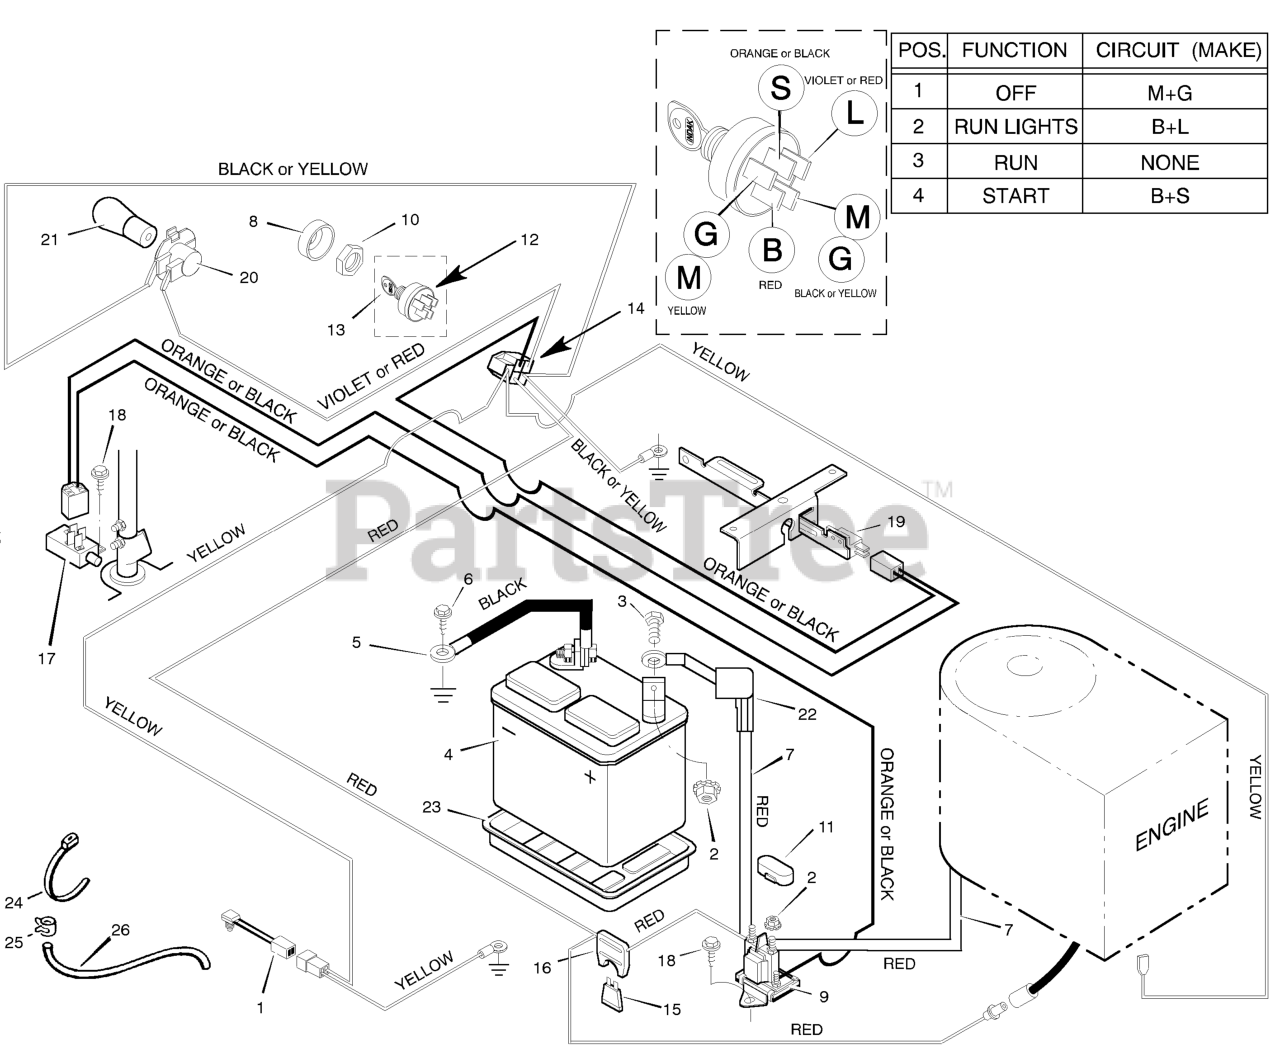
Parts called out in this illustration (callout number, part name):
1	Switch, Seat Sensor
2	Locknut
4	Battery
5	Cable, Battery Ground
7	Cable, Red Battery
8	Cap, Ignition
9	Solenoid
10	Nut, Hex
11	Cover, Solenoid
12	Switch, Ignition
13	Key, Ignition
14	Harness, Chassis Wire
16	Holder, Fuse
17	Switch, Limit
19	Switch, Limit
20	Socket, Light
21	Bulb, Light
22	Cover, Terminal
23	Tray, Battery
26	Tube, Drain
